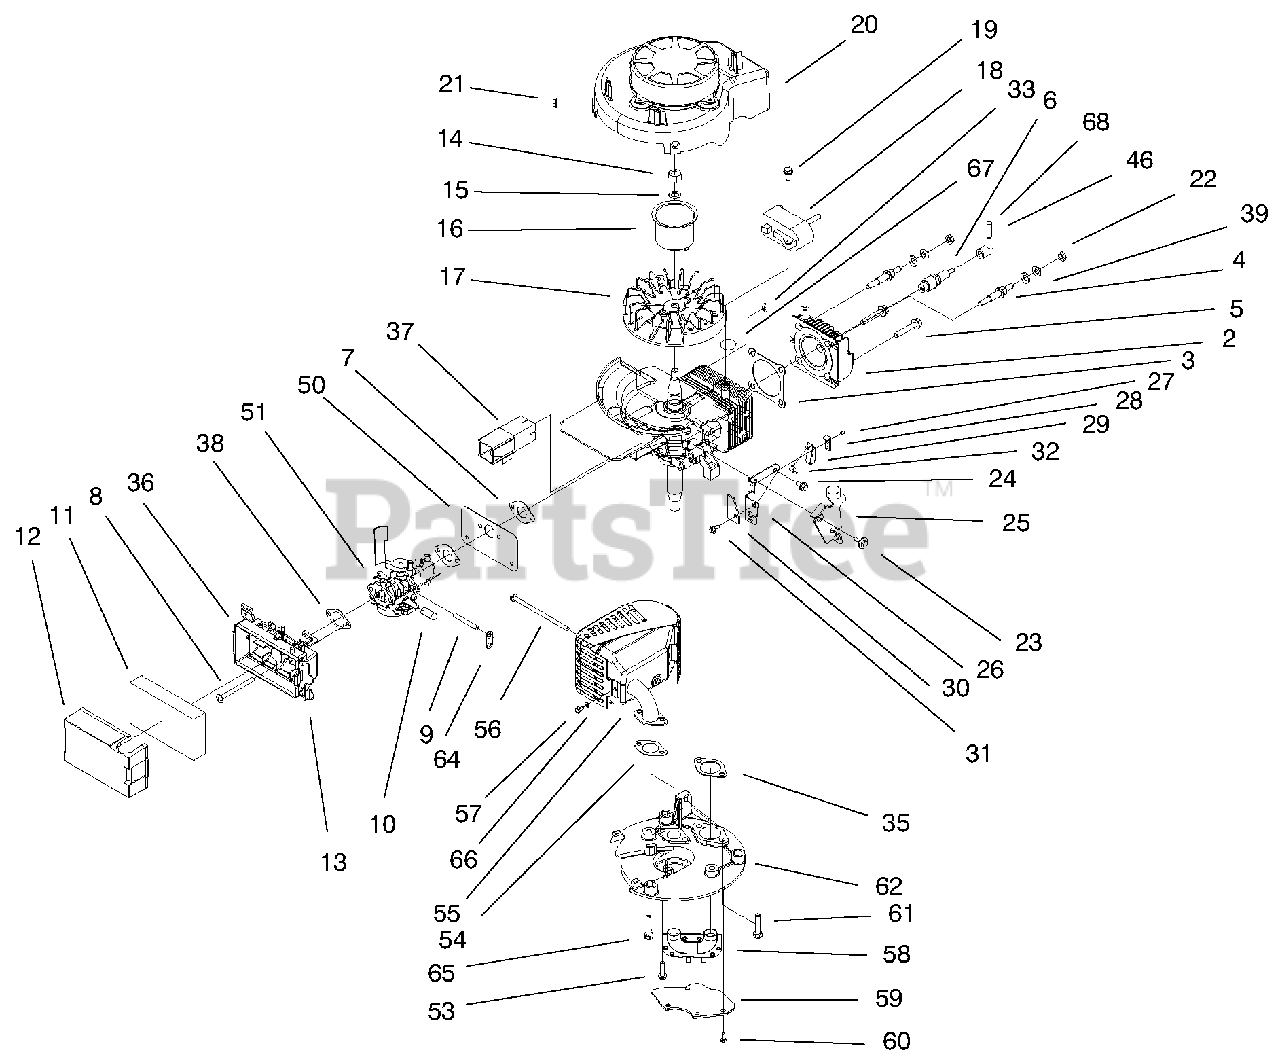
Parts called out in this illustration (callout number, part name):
3	Gasket-Head
6	Spark Plug
7	Intake Gasket
9	Primer Hose
11	Element-Air Filter
12	Cover-Air Filter
13	Retainer-Filter
15	Washer-Lock
16	Cup-Starter
17	Flywheel Machined Recoil
18	Ignition ASM
19	Screw-HWH
20	Shroud & Recoil ASM
21	Screw
22	Nut-Lock
23	Shoulder Screw Brake
24	Screw (Brake)
25	ASM-Brake Plate
26	Plate-Mount Brake
27	Rivet-Self Expand Plas
28	Strap-Insulation
29	Strap-Ground
30	Stop-Ground Strap
31	Screw-Thread Forming
32	Brake Switch Lead Wire
35	Gasket-Exhaust
36	Air Filter Base ASM
38	Gasket-Filter Base
39	Washer-Lock
46	Cover & Terminal
50	Heat Shield
51	Carburetor ASM w/Gaskets
53	Screw-HWH
55	Muffler & Guard
58	Transfer Tube
59	Cover Plate
61	Screw-HH
62	Muffler Plate Machining
64	Retainer Hose
65	Screw-HH
66	Washer-Lock
67	Tie Strap
68	High Tension Lead & Cover
